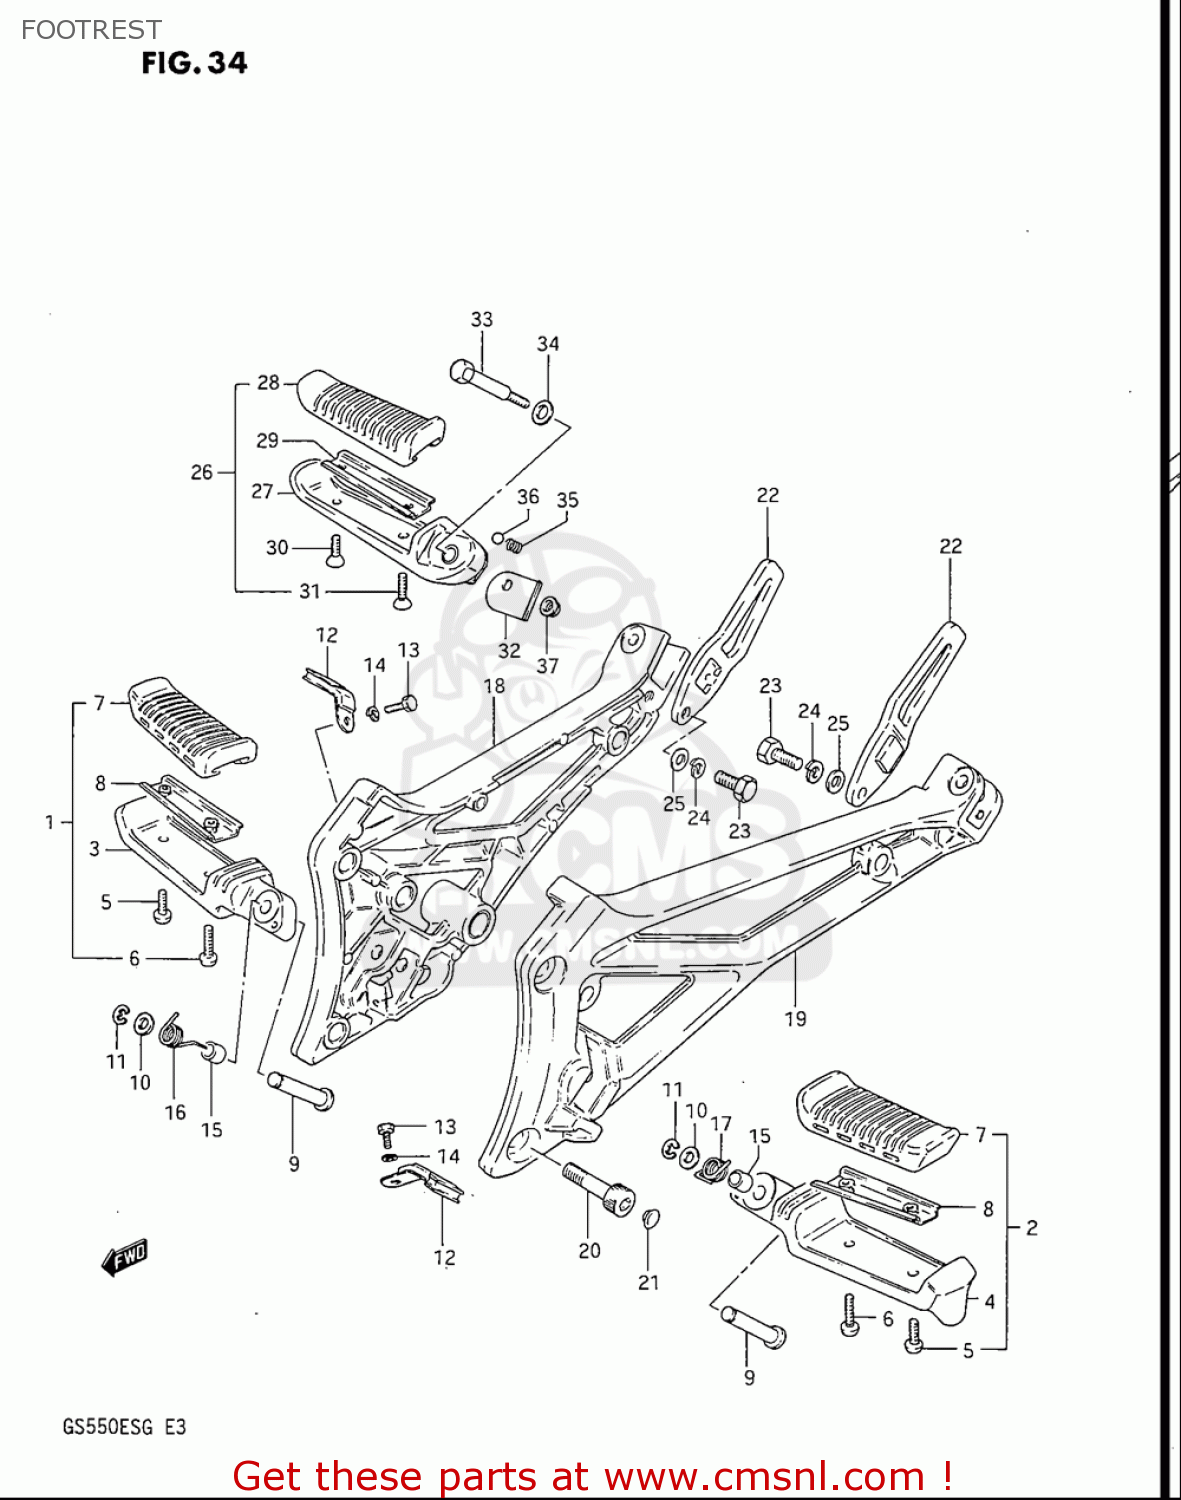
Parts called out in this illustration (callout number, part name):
1	BAR,FR FOOTREST,R
2	FOOTREST ASSEMBLY,FRONT,LEFT
4	FOOTREST,FRONT,LEFT
5	SCREW
6	SCREW
7	RUBBER,FOOTREST
8	PLATE,FR FOOTREST RUBBER
9	PIN
10	SHIM(8.8X14X1)
11	E RING
12	CUSHION,FR FOOTREST
13	BOLT
14	WASHER,LOCK
15	BUSHING
16	SPRING
17	SPRING
20	BOLT 10X27
21	CAP
23	BOLT
24	WASHER,LOCK
25	WASHER
26	FOOTREST ASSY,PILLION,R
28	RUBBER,RR FOOTREST
29	PLATE,RUBBER STOPPER
30	SCREW
31	SCREW
32	PLATE,SPRING STOP,R
33	BOLT
34	WASHER
35	SPRING
36	BALL
37	NUT
